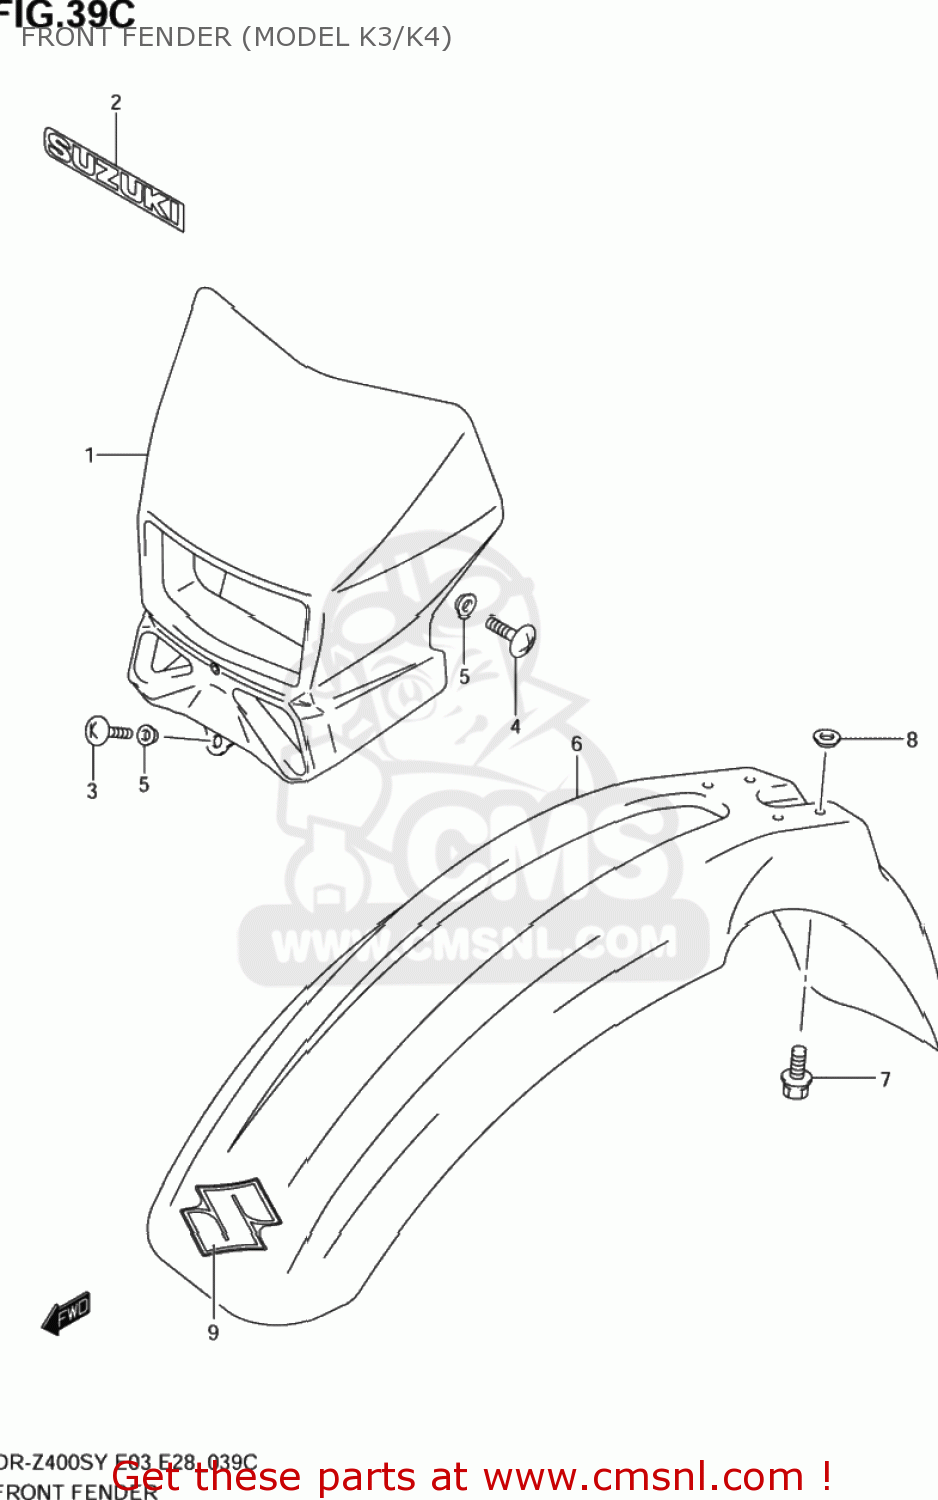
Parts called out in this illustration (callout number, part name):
1	COVER,HEADLAMP
2	EMBLEM,SUZUKI
3	SCREW 5X12
4	SCREW 6X12
5	WASHER
6	FENDER,FR
7	BOLT(6X16)
8	WASHER
9	EMBLEM "S"
